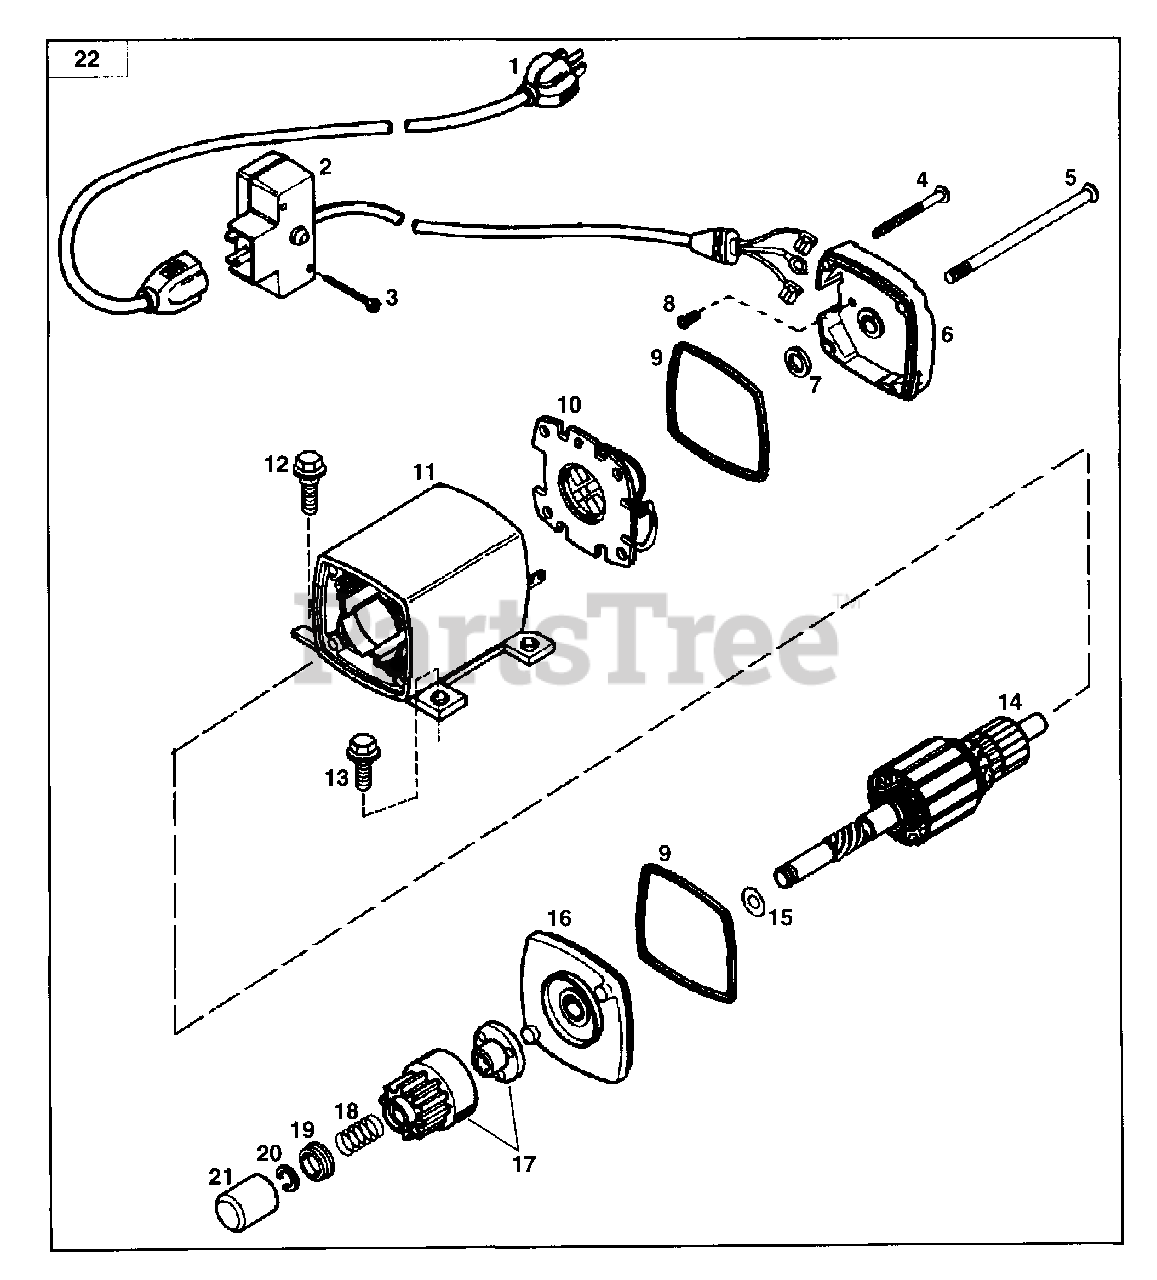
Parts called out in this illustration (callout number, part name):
1	Extension Cord (10'6")
2	Switch Box Ass'y.
3	Screw, 6-32 x 2 1/2"
4	Ground Screw
5	Case Bolt
6	Commutator End Cap Ass'y
7	Thrust Washer
8	Ground Screw
10	Brush Card Ass'y
11	Housing Ass'y
12	Screw, 1/4-20 X 1/2"
13	Screw, Torx T-30, 1/4-20 X 1/2"
15	Thrust Washer
16	Drive End Cap Ass'y.
17	Gear & Nut
18	Anti-drift Spring
19	Spring Retainer
20	Retainer Ring
21	Dust Cover
22	Electric Starter Assembly
